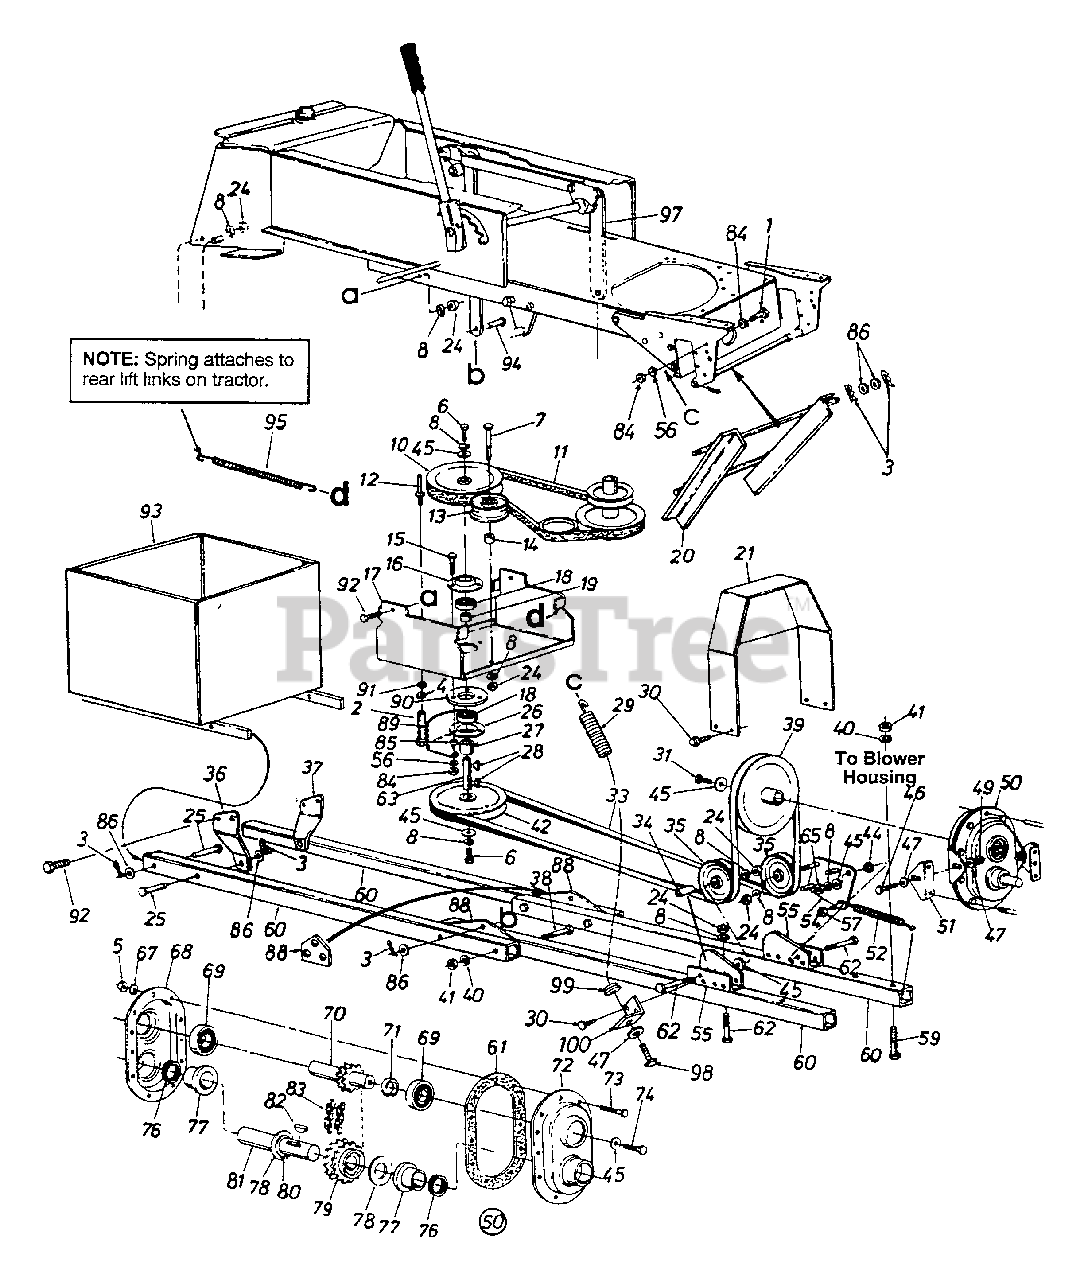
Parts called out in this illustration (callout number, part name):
1	Hex Bolt 5/16-24 x 2" Lg.
2	Clevis Pin Spec. 3/8" Dia. x 2.62" Lg.
3	Intern. Cot. Pin
4	L-Wash. 1/4" I.D.
5	Hex Nut 1/4-28 Thd.
6	Hex L-Scr. 3/8-24 x 1.0" Lg.
7	Hex Bolt 3/8-16 x 2.25" Lg.
8	L-Wash. 3/8" I.D.
10	5/8" "V"-Pulley .79" I.D. x .65" O.D.
11	"V"-Belt
12	Belt Guard Pin
13	Fl-Idler 3.75" O.D.
14	Spacer .385" I.D. x .63" O.D. x .76"
15	Hex Bolt 5/16-24 x 1.50
16	Open Brg. Hsg.
19	Spacer .8" I.D. x 1" O.D.
20	Guide Brkt. Ass'y.
21	Belt Cover Ass'y.
24	Hex Nut 3/8-16 Thd.
25	Clevis Pin .50" Dia. x 1.75" Lg.
26	Brg. Hsg. Ass'y.
27	Spacer .8" I.D. x 1" O.D. x .125"
28	Woodruff Key 3/16" x 5/8" HT
29	Helper Spring
30	Hex Wash. HD-Tap Scr. 5/16-18 x .50
31	Hex L-Scr. 3/8-24 x 1.0" Lg.
33	"V"-Belt
34	Spacer .39" I.D. x .62" O.D. x 1.74" Lg.
35	V-Idler Pulley
39	5/8" "V"-Pulley 7.5" O.D.
40	L-Wash. 1/2" I.D.
41	Hex Nut 1/2-13 Thd.
42	5/8" "V"-Pulley
44	Shld. Spacer
45	Fl-Wash. .4" I.D. x 1.25" O.D. x .16"
46	Hex Bolt 5/16-18 x 1.25" Lg.
47	Bell-Wash. .345" I.D. x .88" O.D. x .06"
49	Hex Nut 5/16-18 Thd.
50	Comp. Chain Gear Box Ass'y.
51	Gear Box Support Brkt.
52	Ext. Spring .6" Lg.
56	L-Wash. 5/16" I.D.
57	Hex Nut 3/8-24 Thd.
59	Hex Bolt 1/2-13 x 3" Lg.
60	Sq. Tubing 43" Lg.
61	Gasket
62	Hex Bolt 3/8-16 x 3" Lg.
63	Shaft-.787" Dia. x 3.81" Lg.
65	Hex L-Nut 3/8-16 Thd.
67	Wave Spring Wash. .27" I.D. x .51" O.D. x .03"
68	Complete Gear Hsg. Half-L.H.
69	Ball Brg. 1" I.D. x 2" O.D.
70	11-2 x .5 Pitch Sprocket Shaft Ass'y.
71	Spacer 1" I.D. x 1.18" O.D. x .44"
72	Comp. Gear Hsg. Half-R.H.
73	Hex Bolt 1/4-28 x 1" Lg.
74	Hex L-Scr. 3/8-24 x 1" Lg.
76	Oil Seal 1.25" I.D.
77	Flange Brg. 1.25" I.D.
78	Fl-Wash. 1.25" I.D. x 2" O.D. x .036"
79	DBL Sprocket 19-2 Teeth x .5" Pitch
80	Snap Ring for 1.25" Dia. Shaft
81	Gear Shaft 1.25 Dia. x 6" Lg.
82	Hi-Pro Key 1/4" x 7/8"
83	40-2 Chain 1/2" Pitch x 25 Links
84	Hex Nut 5/16-24 Thd.
85	Spacer .380" I.D. x .625" O.D. x .227
86	Fl-Wash. .53" I.D. x 1" O.D. x .06"
88	Attaching Plate (46" Decks)
91	Hex L-Nut 1/4-20 Thd.
92	Hex Bolt 3/16 x 1" Lg.
95	Extension Spring
97	Deck Lift Link Ass'y.
98	Hex Bolt 5/16-18 x 1.5" Lg.
99	Spring Insert
